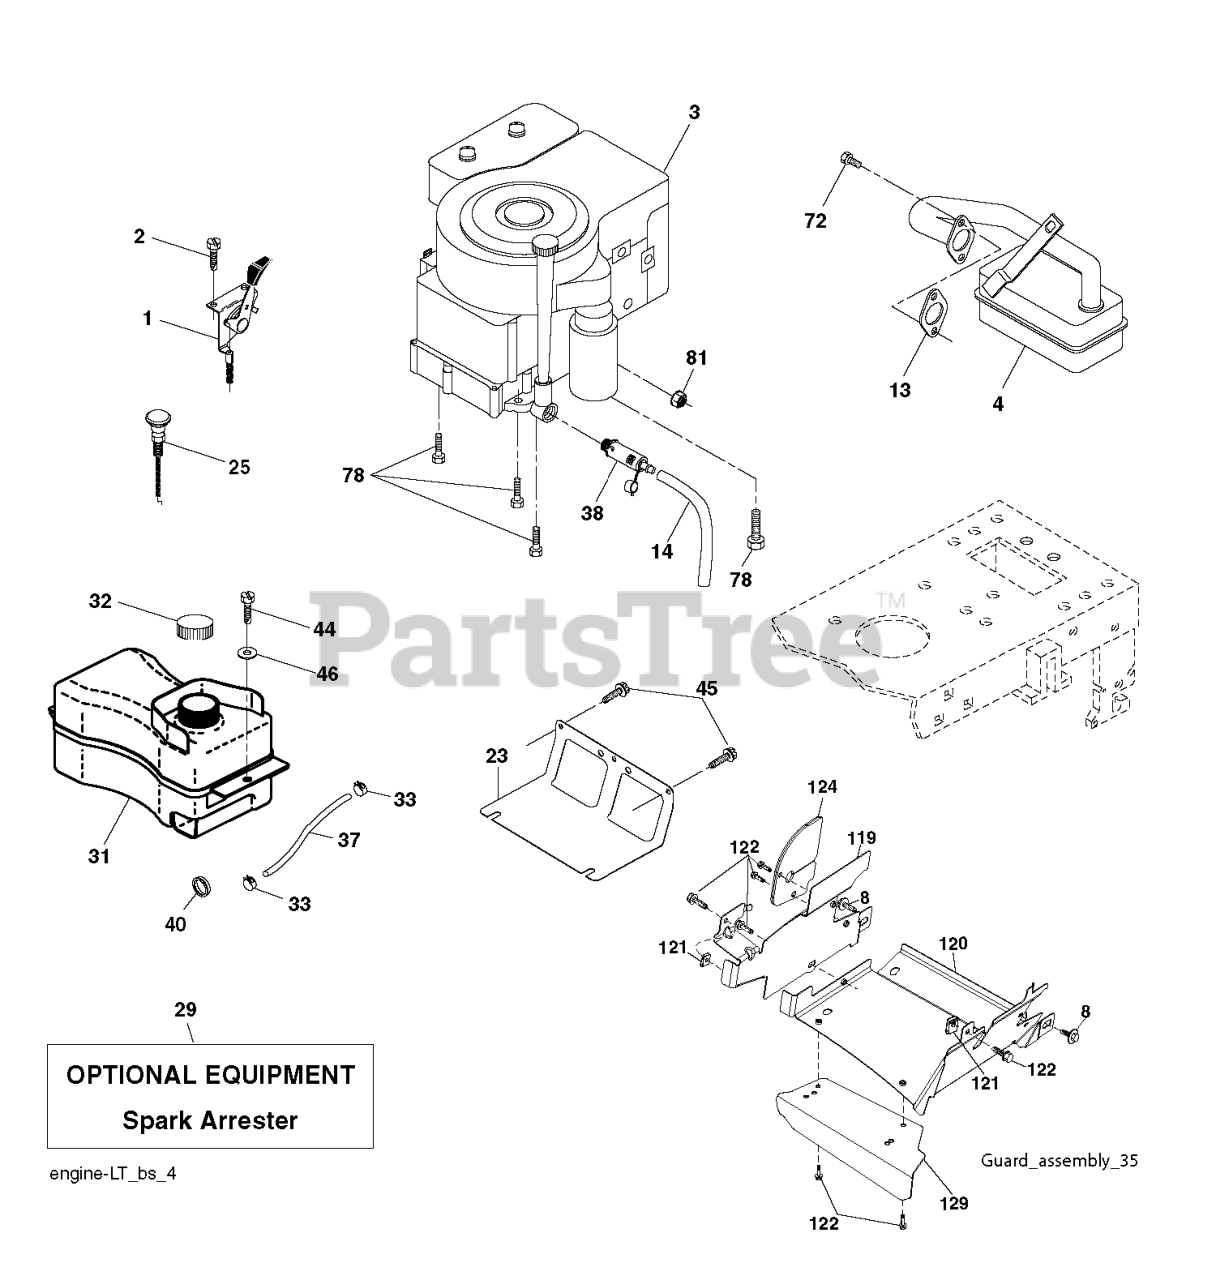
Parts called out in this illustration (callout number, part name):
1	CONTROL.THROTTLE/CHOKE.BLACK
2	SCREW
4	MUFFLER.B&S.MODEL.21.11HP.OHV
8	BOLT.5/16-18UNCX3/4 W/SEMS.BLK
13	REPL BY 532 27 22-93
14	TUBE, DRAIN OIL ASM.
23	SHIELD.BROWNING.DBR.GUARD
25	KNOB.ERGO.EXTENDED.RED (1 2)
29	KIT.SPARK ARRESTOR 794945 B&S
32	FUEL CAP
33	HOSE CLAMP
37	LINE.FUEL.20
38	PLUG DRAIN OIL EASY
40	BUSHING.SNAP.NYL.BLK.
44	SCREW HEXWSHR 1/4-20X3/4
45	SCREW, 3/8-16X3/4
46	WASHER
72	SCREW.SOCKET HD.5/16-1
78	SCREW.3/8-16
81	NUT
122	SCREW.1/4-20X5/8
